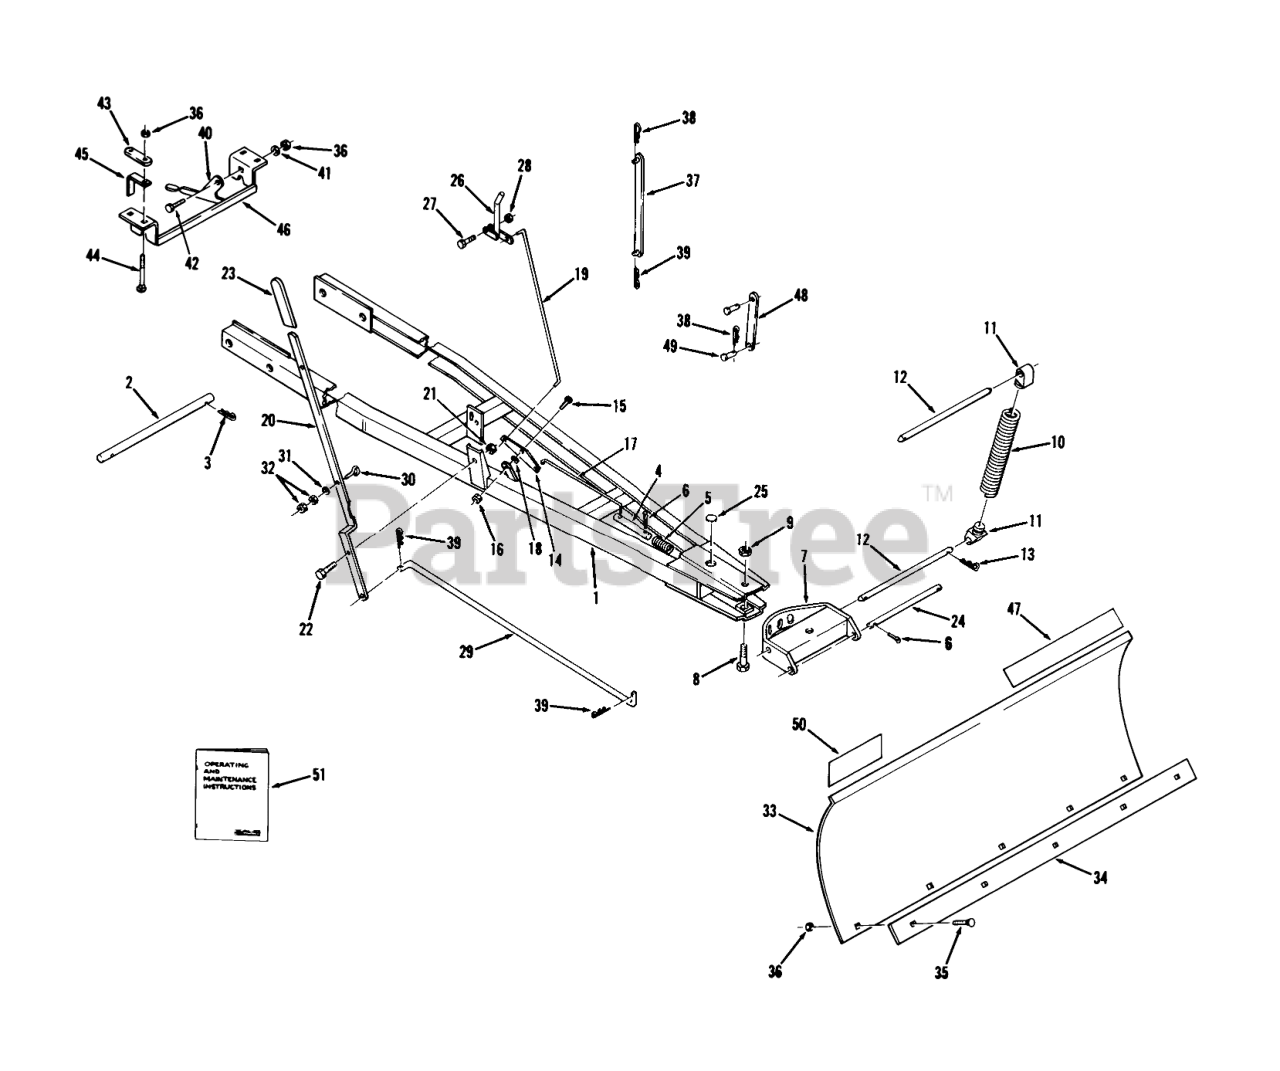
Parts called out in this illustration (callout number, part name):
3	Hairpin
5	SPRING-COMPRESSION
12	ROD-PIVOT, BLADE
13	Hairpin
17	LOWER INDEX ROD
23	GRIP
24	ROD-LOWER
25	PLUG
33	ORD 109593 & 109596
38	Hairpin Cotter
39	Hairpin
40	PLATE-LATCHING
43	BRACKET-REAR LINK MOUNTING
45	SPACER-BRACKET
48	LINK-LIFT
51	Operating and Maintenance Instructions
